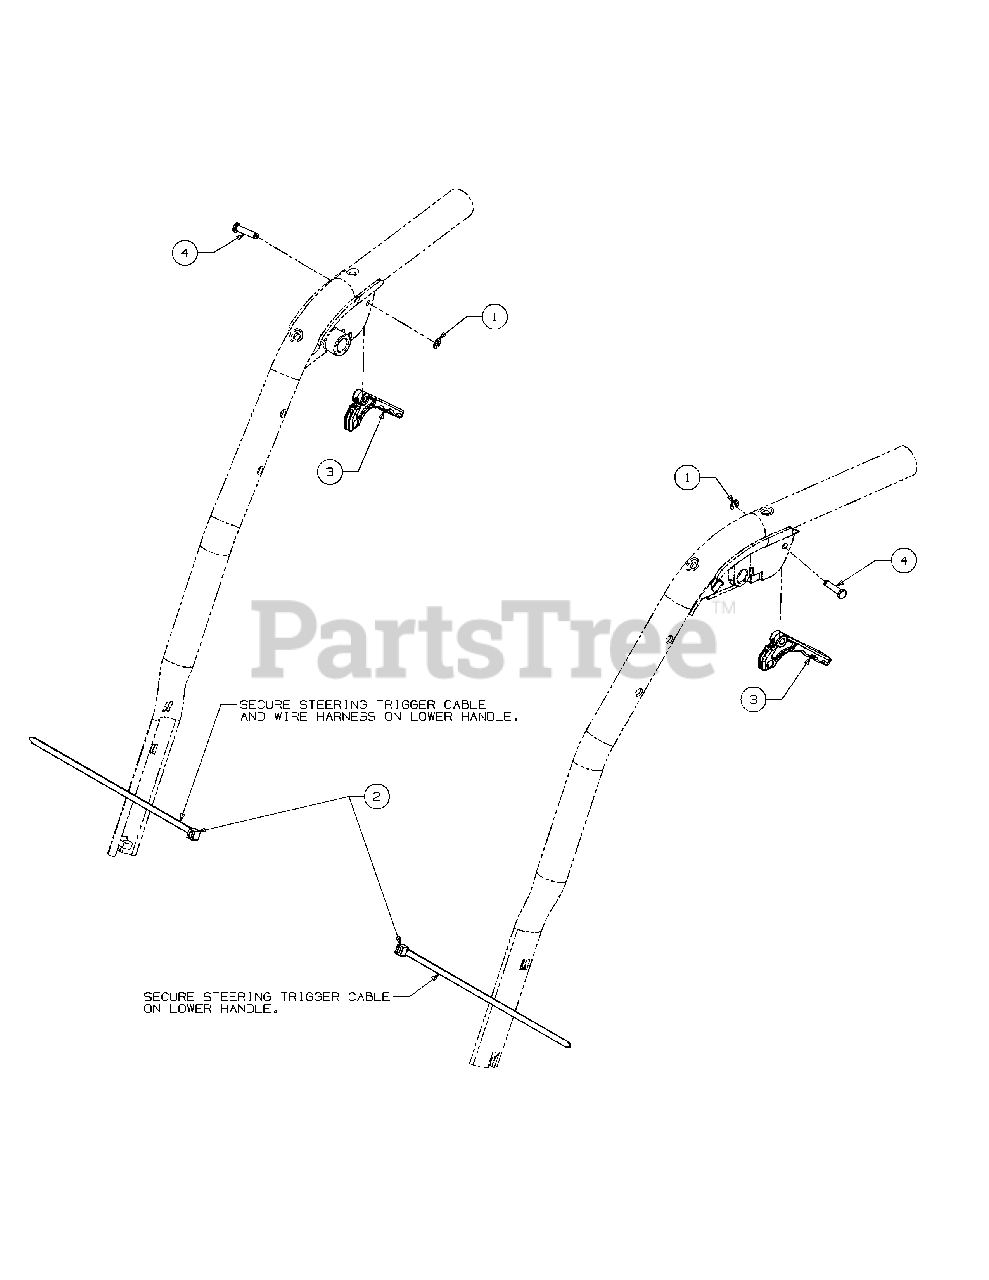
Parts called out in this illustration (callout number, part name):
1	RING
2	TIE-CABLE 7"
3	TRIGGER-STRG CNTRL
4	PIN-STRG TRGR 3/16
